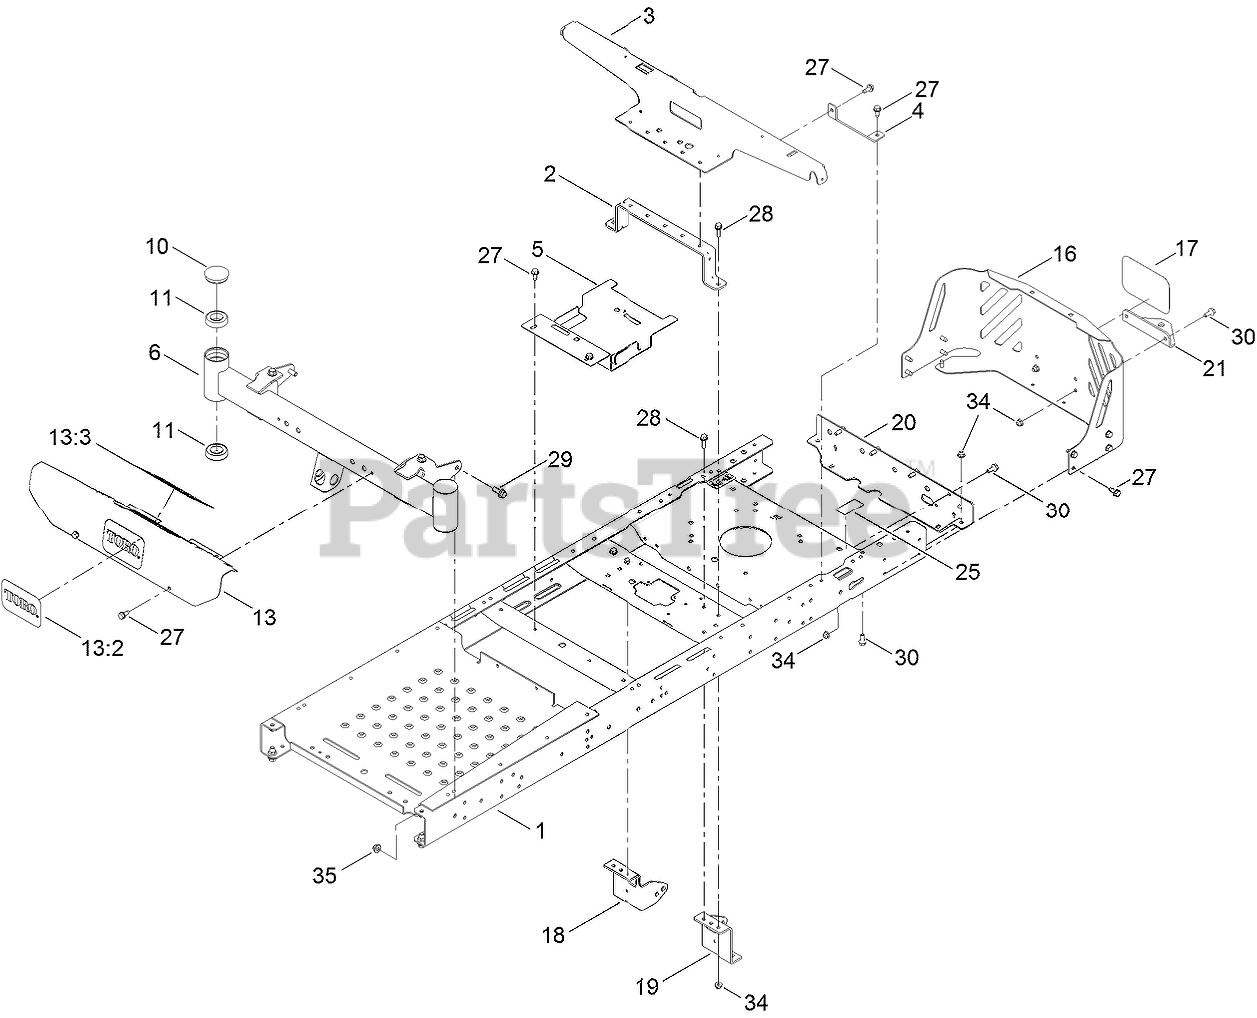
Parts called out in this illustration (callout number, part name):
1	FRAME ASM
2	BRACE-SEAT, REAR (NARROW)
3	SUPPORT-POD
4	SUPPORT-TANK, REAR
5	BRACKET-BATTERY
6	AXLE-FRONT, NARROW
10	CAP-GREASE
11	BEARING-BALL
13	FOOTREST ASM
13:3	DECAL-DANGER
16	GUARD-ENGINE, NARROW
17	DECAL
18	MOUNT-HYDRO, FRONT (RIGHT)
19	MOUNT-HYDRO, FRONT (LEFT)
20	CROSSMEMBER-REAR, NARROW
21	BRACKET-HITCH
25	DECAL-BYPASS
27	SCREW-HWHTF
28	SCREW-HHF
29	SCREW-HHF
30	SCREW-HHF
34	NUT-HF
35	NUT-HF, NI
